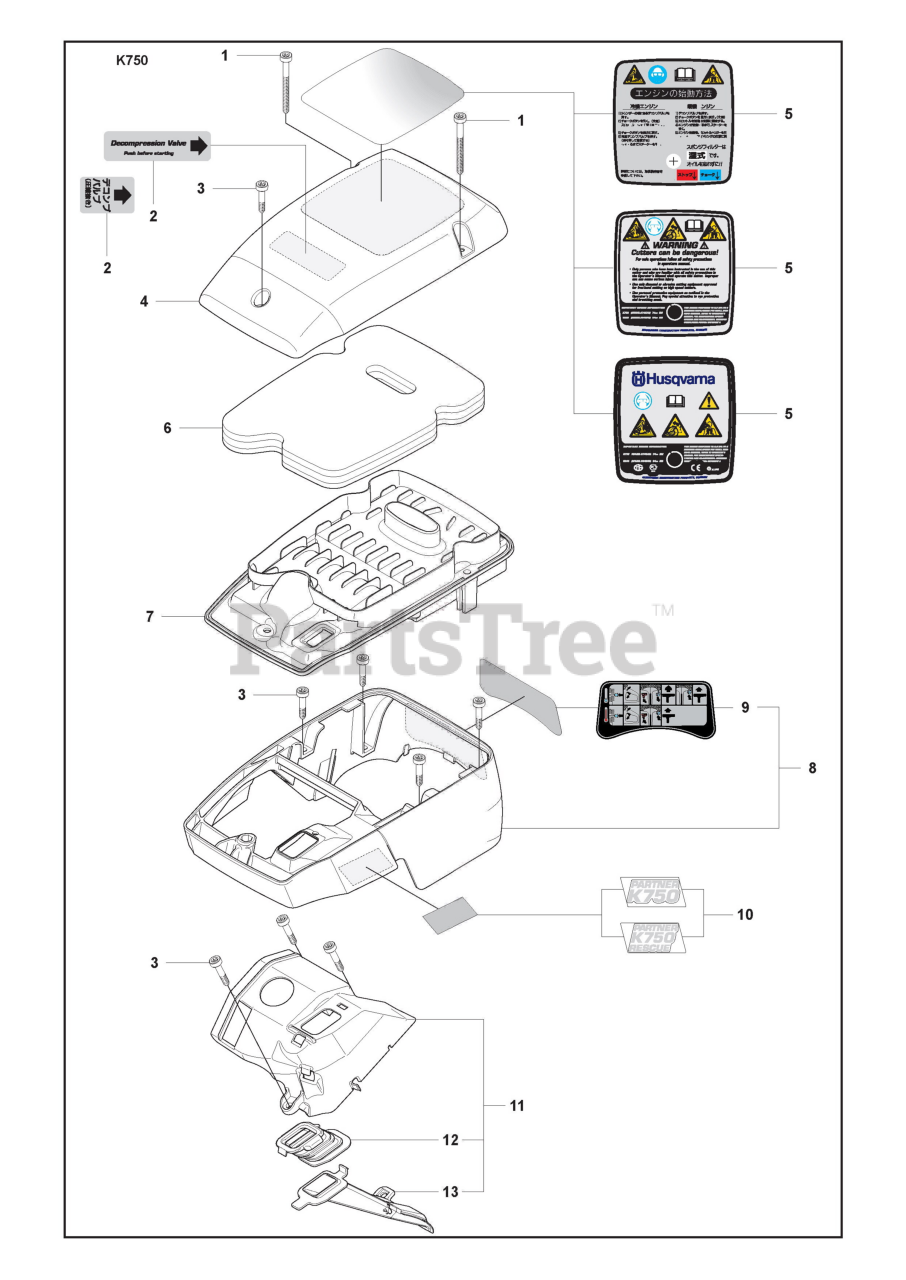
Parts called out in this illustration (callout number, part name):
2	LABEL
4	FILTER COVER
5	LABEL
7	FILTER BOTTOM
8	CYLINDER COVER ASSY
10	LABEL
11	COVER
12	BELLOWS
13	AIR NOZZLE
